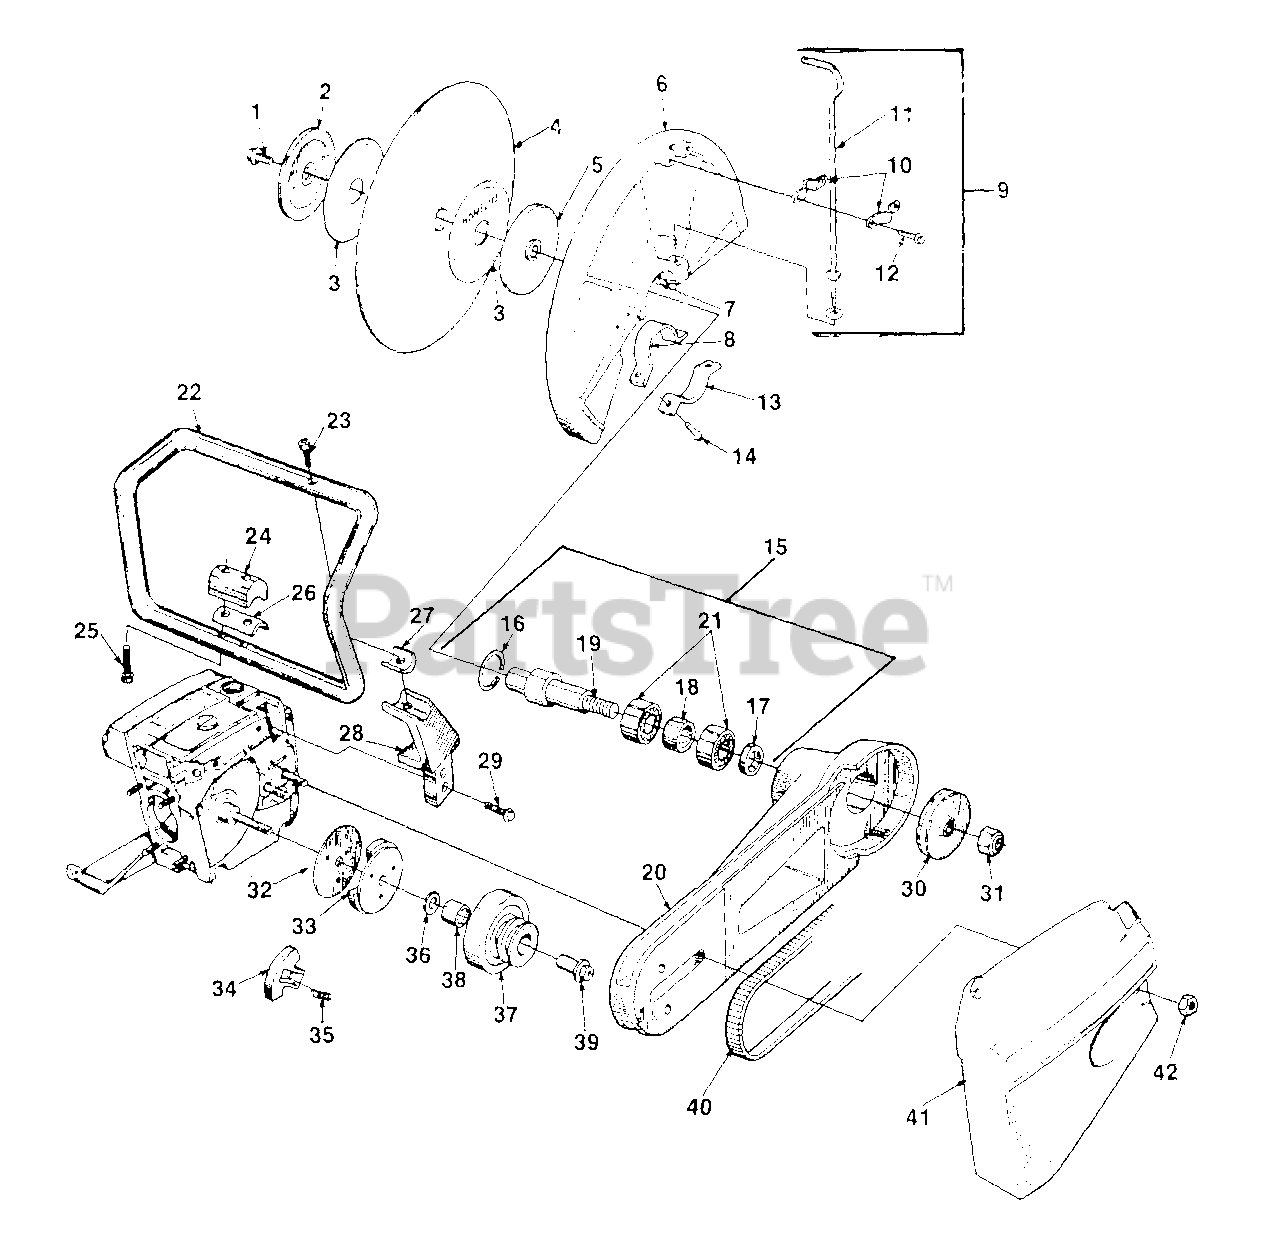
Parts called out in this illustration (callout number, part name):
1	BOLT-Blade
2	WASHER-Outer
3	SPACER-Blotter
4	WHEEL-Resinoid
5	WASHER-Inner
6	BLADE GUARD & SLEEVE
7	PIN-Spirol
8	SLEEVE-Blade guard
9	HOOK BOLT & CLAMP ASSEMBLY
11	BOLT-Hook
12	SCREW-1/4-20 x 1/2
13	CLAMP-Blade guard
14	SCREW-1/4-20 x 13/16
15	BLADE ARM KIT
16	RING-Retaining
17	SPACER-Pulley
18	SPACER-Inner
19	SHAFT-Blade
20	ARM-Blade
21	BEARING-Ball
22	HANDLE BAR
23	SCREW-Nylock 1/4-20 x 1
25	SCREW-Nylock 1/4-20 x 1 7/8
26	MOUNT-Shock
27	MOUNT-Shock
28	BRACKET-Handle bar
29	SCREW-Hex hd. 12-24 x 3/4
30	PULLEY-Driven
31	NUT-Stop 7/16-14
32	COVER-Clutch
33	PLATE-Clutch back
34	SHOE-Clutch
35	SPRING-Clutch
37	PULLEY-Bearing & Arm
38	BEARING
39	RACE-Inner bearing
40	BELT-Drive
41	COVER-Drivecase
42	NUT-3/8-16
